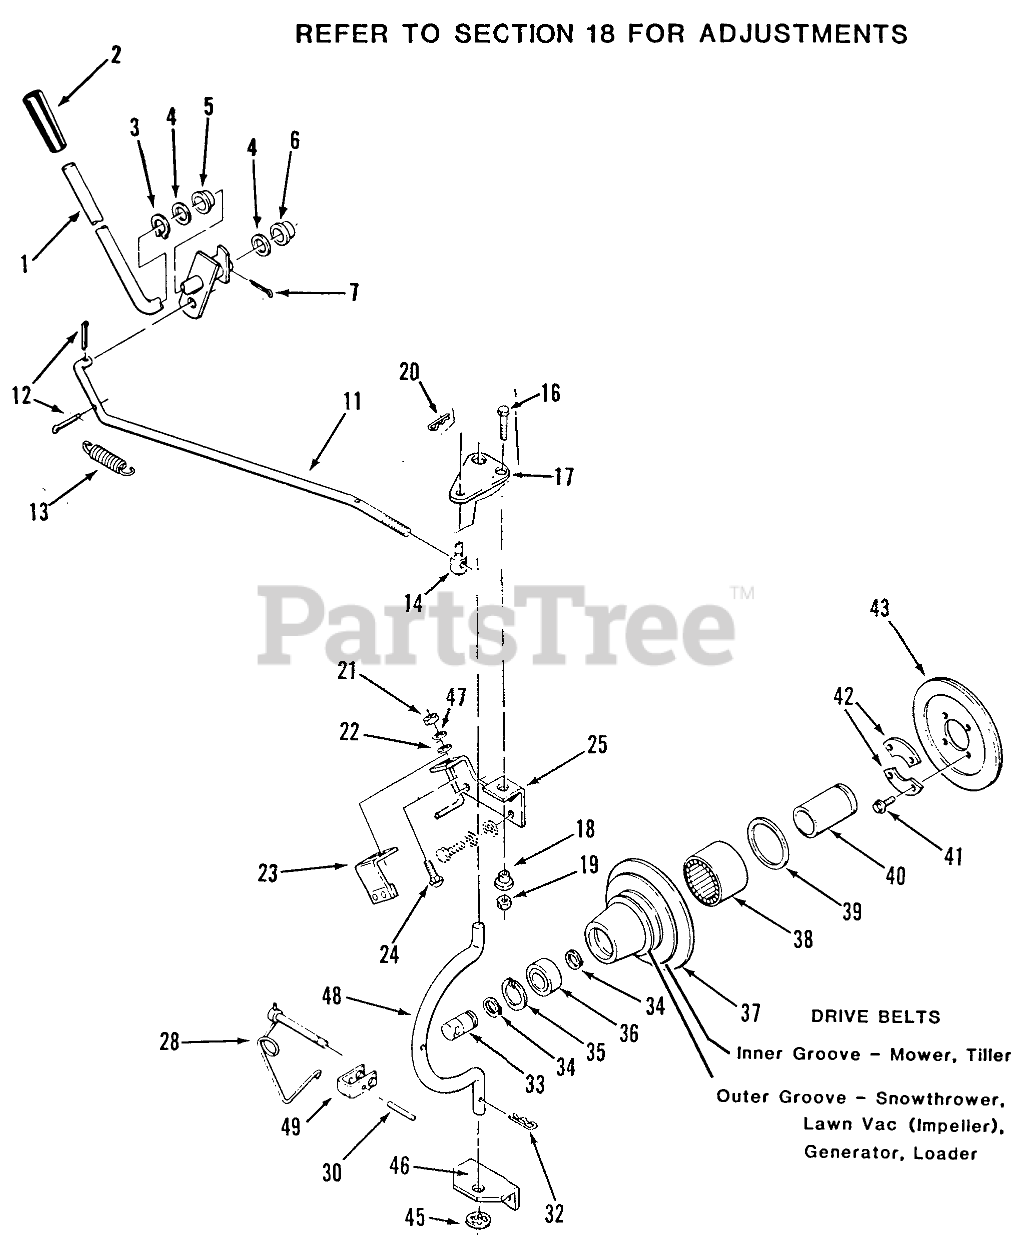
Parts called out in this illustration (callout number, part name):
1	ASSY PTO CLUTCH LEVE
2	GRIP
3	Grip Ring
4	SHIM-WASHER
5	BUSHING-NYLINER
6	NYLINER BUSHING
7	Pop Rivet
11	ROD-PTO CLUTCH
12	Pop Rivet
13	SPRING
14	TRUNNION
16	BOLT
17	PLATE
18	SPACER-LIFT LINK
19	Nut
20	Hairpin Cotter
21	Nut
23	ASM-Bracket
24	Bolt-Carriage
25	BRACKET WA ENG. B
28	LOCKING PIN ASM
32	Hairpin
33	SHAFT-PTO
34	RING-SNAP, EXTERNAL
35	Ring-Snap
36	BEARING-BALL
37	Housing-Clutch
38	BRG-NEEDLE OPEN END
39	SEAL-OIL
40	RACE-BEARING
41	H H C S
42	RETAINER
43	Clutch Plate & Facing
45	RING-REINFORCED CIRC
46	Axle
47	Washer
48	ROD-HOUSING
49	CLEVIS
